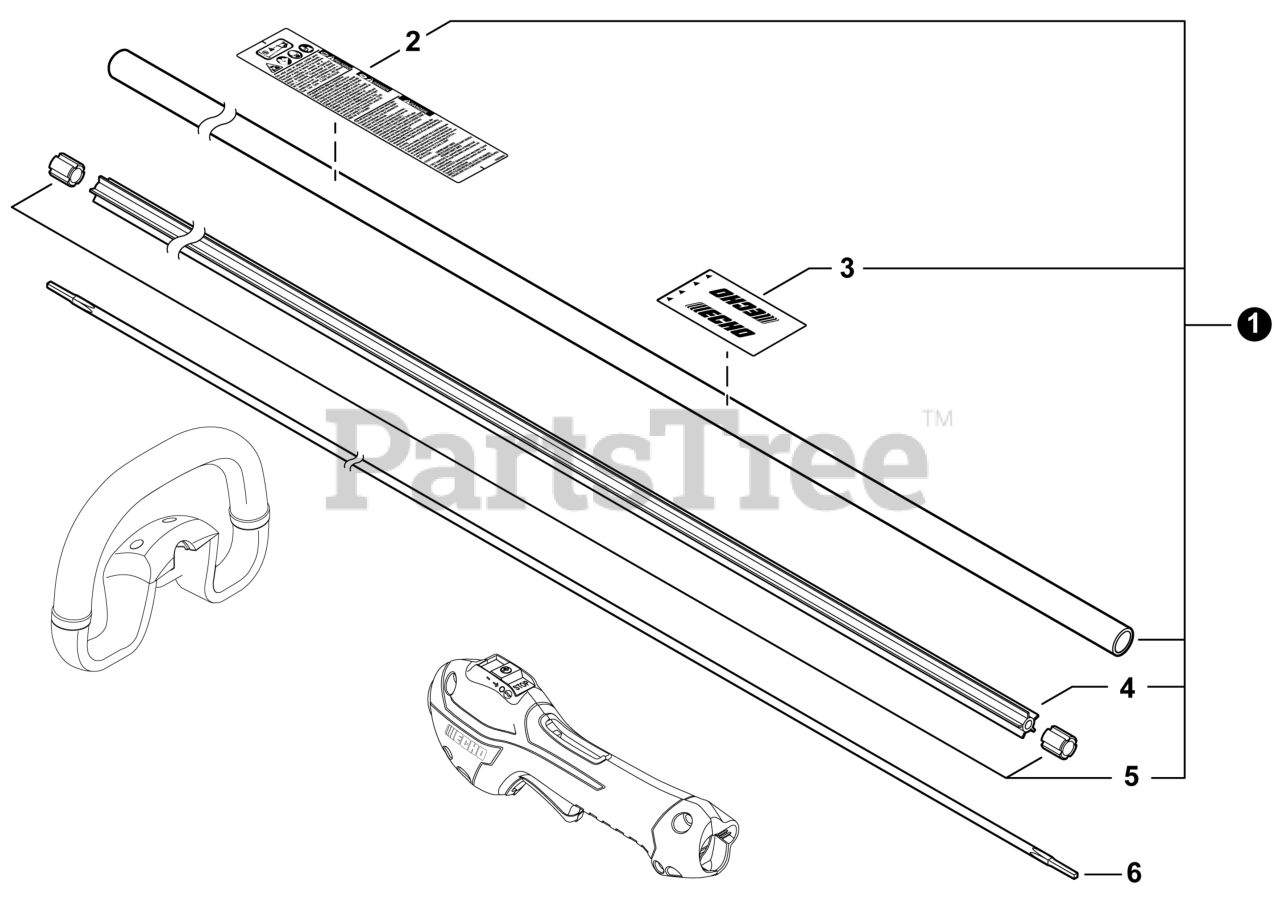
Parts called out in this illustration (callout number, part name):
1	MAIN PIPE ASSY
2	LABEL - CAUTION
3	LABEL - HANDLE LOCATION
4	LINER, FLEXIBLE 21.6x1420
6	DRIVESHAFT - FLEXIBLE
